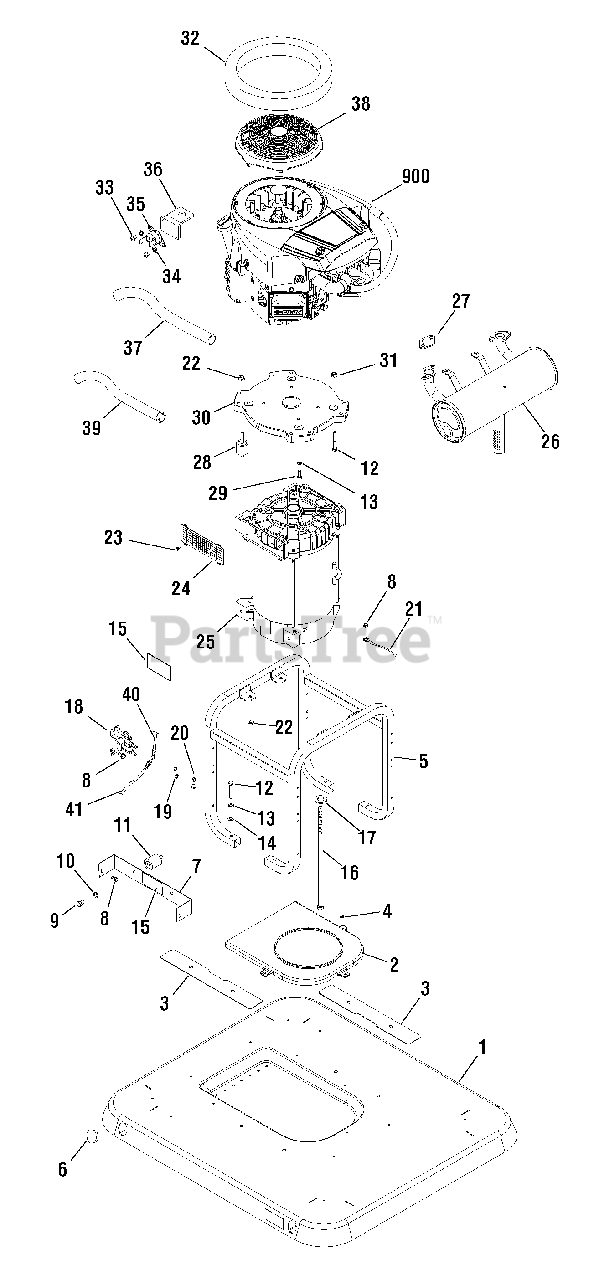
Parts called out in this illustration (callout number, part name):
8	BOLT
9	* CAPSCREW, Hex Head, 3/8-16 x 1/2
10	* WASHER, Lock, 3/8
11	MOUNT, Vibration
12	* CAPSCREW, Hex Head, 5/16-18 x 2
13	* WASHER, Lock, M8
14	* WASHER, Flat, M8
15	DECAL
16	BOLT
18	SOLENOID-STARTER
19	* WASHER, Lock, 1/4
20	* NUT, 1/4-20
25	ALTERNATOR
28	MOUNT-VIBRATION
29	* CAPSCREW, Hex Head, 5/16-18 x 1
33	SCREW
36	PLATE-TEMP SWITCH
900	** ENGINE
